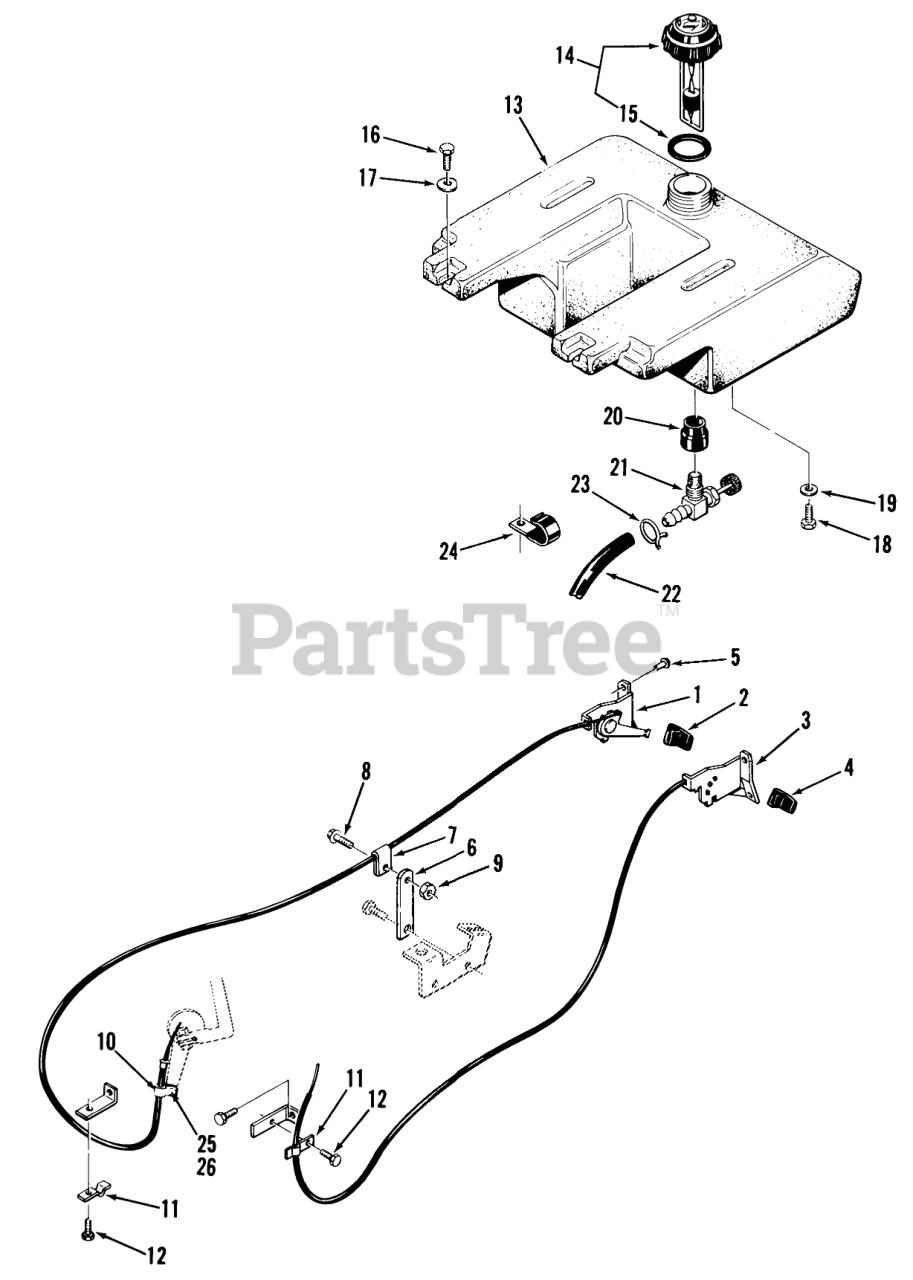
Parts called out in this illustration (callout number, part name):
1	THROTTLE CONTROL
1	Throttle Control
2	KNOB-THROTTLE
3	CONTROL-CHOKE
4	KNOB-CHOKE
5	Pip Rivet
6	Strap
7	THROTTLE CONTROL CLP
8	Screw
9	Nut
10	Clip
11	CLAMP-CABLE
12	Screw #10-24 X 3/8 C-81 Only
13	TANK-FUEL
14	ASSY-GAUGE CAP
15	GASKET-GAS CAP
16	Bolt
17	Washer
18	Bolt
19	Lockwasher
20	BUSHING
21	VALVE-FUEL
22	Fuel Line
23	Clamp
24	CLIP
25	Screw
26	Hex Nut
